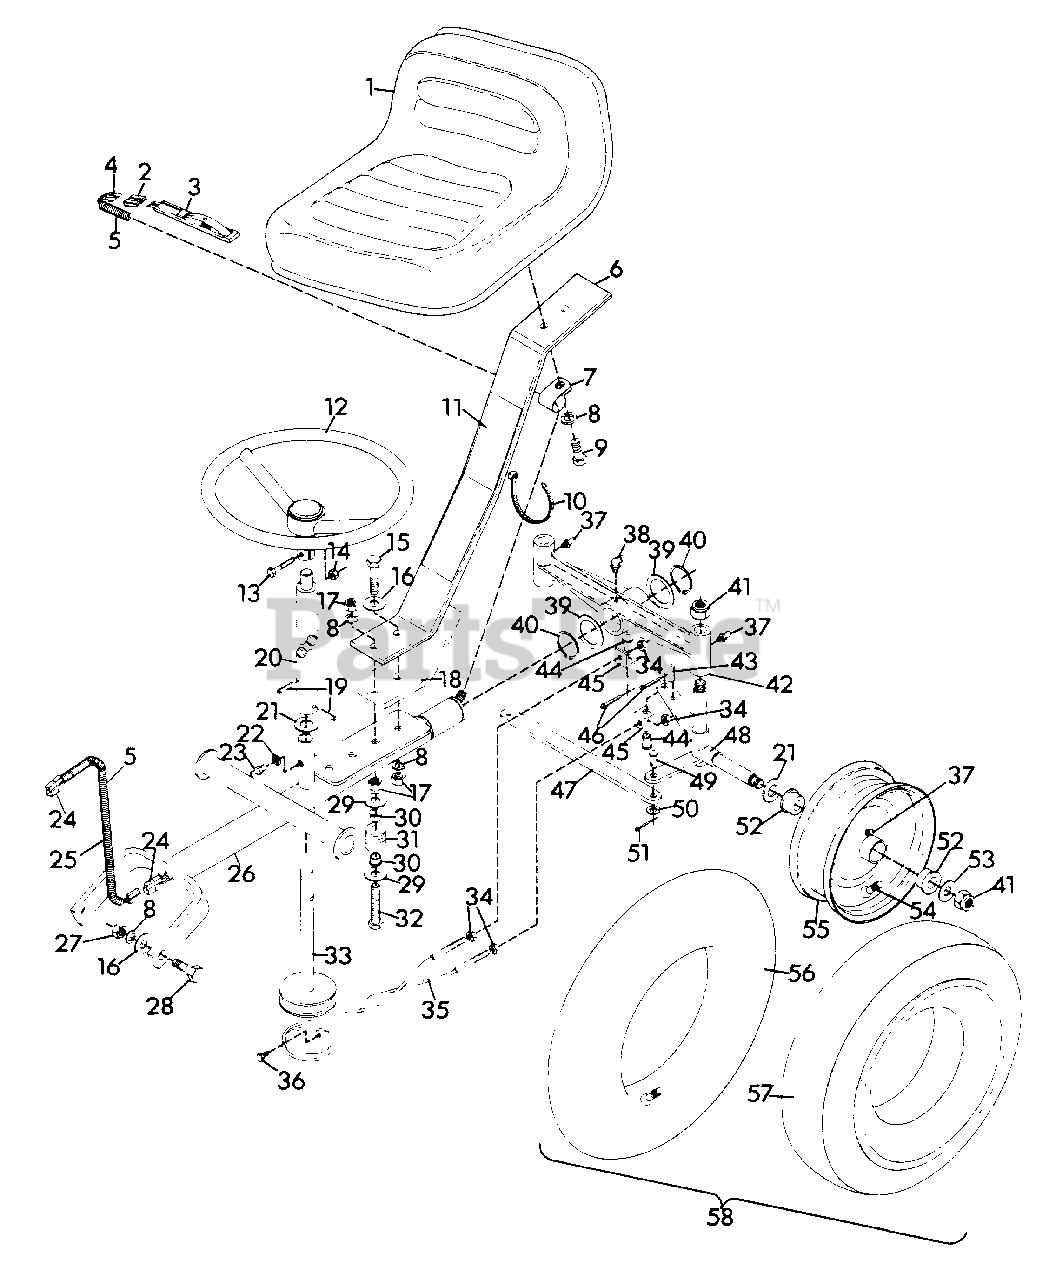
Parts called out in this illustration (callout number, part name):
1	SEAT, STEERING SULKY
2	CONNECTOR, 2-WIRE SWITCH
3	SWITCH, SEAT
4	HARNESS, WIRING
5	CONDUIT, 3/8 PLASTIC
6	ASSEMBLY, SEAT SPRING AND DECAL
7	CLIP, TUBE
8	WASHER, LOCK 1/2 REG.
9	BOLT, HEX 1/2-13X1.00
10	TIE WRAP, BLACK
11	DECAL, WARNING
12	WHEEL, STEERING
13	BOLT, HEX 3/8-16X1.375
14	NUT, LOCK 3/8-16
15	BOLT, HEX 1/2-13X3.50
16	WASHER, FLAT .563X1.375X.109
17	NUT, JAM 1/2-13 HEX
18	PLATE, REINFORCEMENT
19	PIN, SPRING .25X1.125
20	COLUMN, STEERING
21	WASHER, FLAT .812X1.496X.134
22	WASHER, LOCK 1/4 INTERNAL TOOTH
23	FITTING, LUBE 1/4-28
24	CONNECTOR
25	HARNESS, EXTENSION
26	WELDMENT, CHASSIS SULKY
27	NUT, HEX 1/2-13
28	BOLT, HITCH
29	WASHER, FLAT .531X1.000X.063
30	BUSHING, CABLE GUIDE PULLEY
31	PULLEY, CABLE GUIDE
32	BOLT, 1/2-13X5.0
33	REEL, ASSEMBLY
34	NUT, HEX 5/16-18
35	CABLE, STEERING
36	BOLT, HEX 1/4-28X.50
37	FITTING, LUBE 1/4-28
38	FITTING, LUBE 90 DEGREE
39	WASHER
40	RING, RETAINING
41	NUT, LOCK 5/8-18 L.T.
42	BAR, CROSS
43	PIN, SPRING .25X1.875
44	PIN, SWIVEL
45	BRACKET, SWIVEL
46	PIN, COTTER .125X1.25
47	BAR, TIE
48	WELDMENT, AXLE L.H.
48	WELDMENT, AXLE R.H.
49	PIN, CLEVIS .375X.750
50	WASHER, FLAT .406X.812X.065
51	PIN, COTTER .094X.75
55	BUSHING, WHEEL
56	WASHER, FLAT .656X1.312X.095
57	ASSEMBLY, VALVE STEM
58	WHEEL, ASSEMBLY LESS TIRE/TUBE
59	TUBE
60	TIRE
61	WHEEL, SULKY ASSEMBLY COMPLETE(INCLUDES ITEM NOS. 37,52,54,55,56,57)
